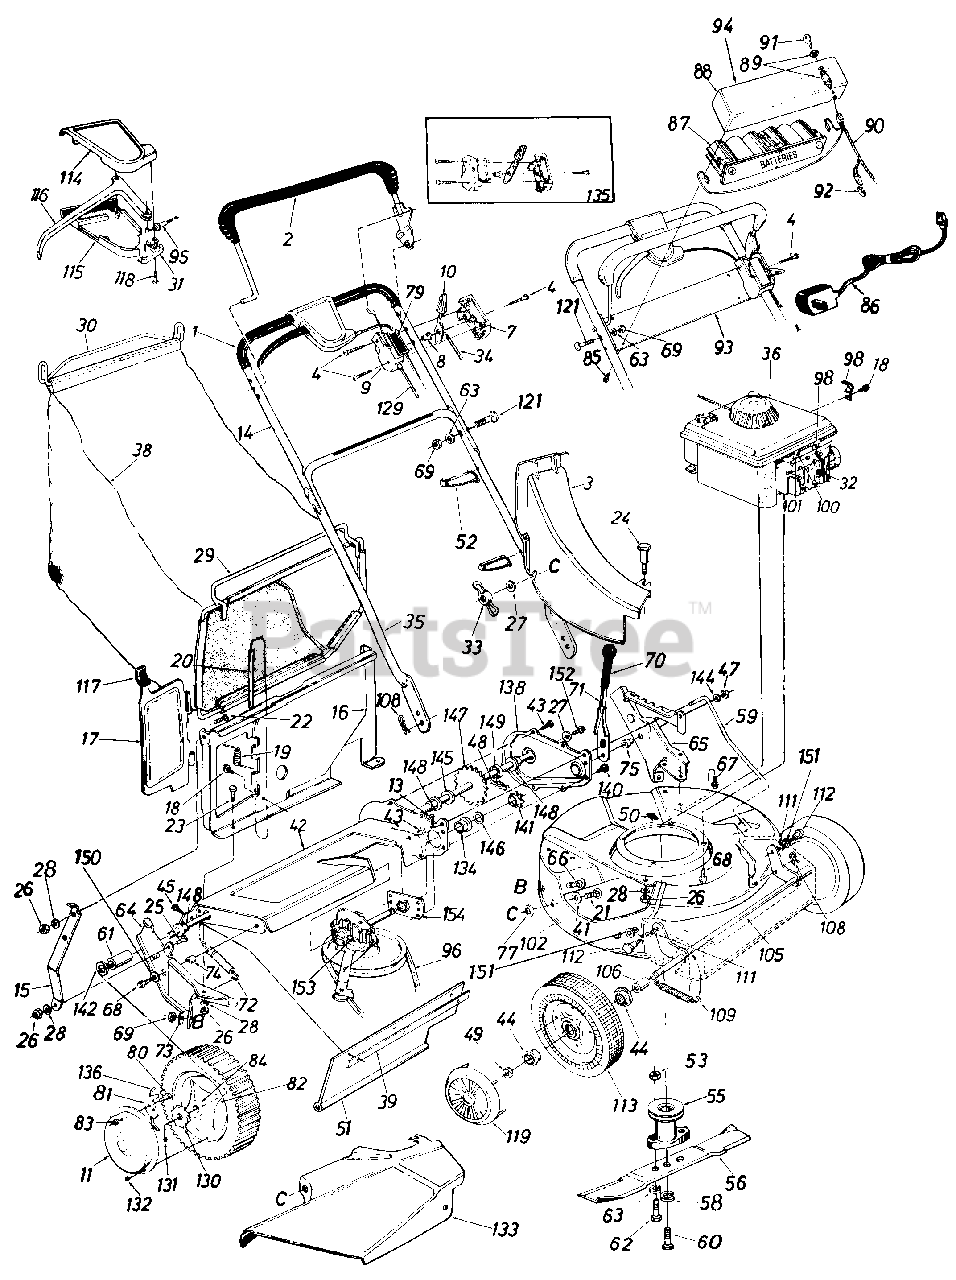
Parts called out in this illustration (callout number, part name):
2	Control Handle Ass'y. L.H.
3	Top Discharge Chute Ass'y.
4	Truss Mach. Scr. #12 x 1.50" Lg.
7	Control Panel Half
8	Control Disc Pin
9	Clutch Panel Half
10	Throttle Control Lever
11	Hub Cap
13	Cotter Pin 3/32" Dia. x .75"
14	Upper Handle-Chrome
15	Panel Support Brkt.
16	Top Catcher Panel
17	Top Door
18	Hex B-Tap Scr. #10 x .38"
19	Torsion Spring
20	Pivot Pin
21	Carriage Bolt 1/4-20 x .62"
22	Truss Mach. Scr. 1/4-20 x 3/4" Lg
23	Hex Bolt 1/4-20 x .50" Lg.
24	Shoulder Bolt .312 Dia. x .18 Lg. Special
25	Hex Bolt 1/4-20 x .62" Lg.
26	Hex Nut 1/4-20 Thd.
27	Bell-Wash. 1/4" I.D.
28	L-Wash. 1/4" I.D.*
29	Front Grass Catcher Frame
30	Grass Catcher Handle
31	S.P. Control Cover
32	Spark Plug Insulator
33	Wing Nut
34	Throttle Control Wire 58"
35	Lower Handle-Chrome
36	Engine
38	21" Top Discharge Grass Bag
39	Retaining Strip
41	Fl-Wash. .344" I.D. x .62"
42	Chain-Axle Ass'y.
43	Hex B-Tap Scr. 1/4" x .38" Lg.
44	Flange Ball Bearing 1/2" I.D.
45	Hex AB-Tap Scr. 1/4 x .62"
47	Hex Patch L-Nut 3/8-24 Thd.
48	#48 Chain .500" Pitch x .30 Links
49	Hex L-Nut 1/2-20 Thd.
51	Rear Flap 3.75" x 17.30" Lg.
52	Cable Tie
53	Hex Nut 5/16-24 Thd.
55	Blade Adapter w/Pulley
56	21" Blade
58	Bell-Wash. .39" I.D. x 1.380" O.D.
59	Height Adj. Rod 19.42" Lg.
60	Hex Bolt 3/8-24 x 2.25" Lg. (Grade 5)
61	Spacer .513" I.D. x .703" O.D. x .69" Lg.
62	Hex Bolt 5/16-24 x 1.00" Lg. (Grade 5)
63	L-Wash. 5/16" I.D.
64	R.H. Handle Wheel Brkt. Ass'y.
65	L.H. Handle Wheel Brkt. Ass'y.
66	Carriage Bolt 5/16-18 x .62"
67	Hex Wash. Hd. B-Tap Scr. 5/16-1 8
68	Hex Wash. Hd. TT-Tap Scr. 3/8-1 6
69	Hex Nut 5/16-18 Thd.
71	Height Adj. Lever
72	Extension Spring .50" O.D. x 3.80" Lg.
73	Bell-Wash. 5/16" I.D.
74	Spacer .385" I.D. x .502" O.D. x .270" Lg.
75	Shld. Spacer .500" Dia. x .100
77	Bolt Retainer 1/4 x-.50" O.D.
79	Control Label
80	Shld. Scr. .342" Dia. x .268
81	Pawl
82	Wheel Ass'y. Comp.-Rear 8 x 1 .75
83	Hex Ins. L-Nut 1/4-20 Thd.
84	Flange Ball Bearing 1/2" I.D.
85	Truss Hd. Scr. #12 x 1.5" Lg.
86	Battery Charger
87	12 Volt Battery
88	Upper Battery Tray
89	Key Switch
90	Wire Harness
91	Key
92	Plug
93	Lower Battery Tray
94	Instruction Label
95	S.P. Cable 50" Lg.
96	"V"-Belt
98	Casing Clamp
100	Hex B-Tap Scr. #10 x .62"
101	Casing Clamp
106	Sleeve .526" I.D. x .690" O.D. x .880" Lg.
108	Intern. Cotter Pin 5/16" Dia.
109	Extension Spring .50" O.D. x 3.20" Lg.
111	Intern. L-Wash. 3/8 I.D.
112	Shld. Bolt .623" Dia. x .425
113	Front-Wheel Ass'y. Comp. 7x 1.50
114	Self-Propelled Control Cover
115	Self-Propelled Control Cover
116	Control Lever
117	Door Grip
118	Fl-"C"-Sunk Hd. Tap Scr. #10 x .75" Lg.
119	Hub Cap-Plastic
121	Curved Carr. Bolt 5/16-18 x 1.38" Lg.
129	Control Cable-43" Lg.
130	Ratchet Wheel 1.62" O.D.
131	Cotter Pin 1/8" Dia. x 1.00" Lg.*
132	Pan Hd. Tap Scr. #12 x .50" Lg.
133	Side Chute Deflector Ass'y
134	Flange Bearing
135	Kit-Control Housing Comp.
136	Spring-Nylon
138	Chain Cover
140	Hex Wash. S-Tap Scr. 1/4-20 x.50" Lg.
141	Sprocket-Shaft Ass'y.
142	Fl-Wash. .510" I.D. x 1.0" O.D.
144	Fl-Wash. .385" I.D. x .87" O.D.
145	Fl-Wash. .51" I.D. x 1.0" O.D.
146	Fl-Wash. 3/8" I.D.
147	Rear Shaft Ass'y. 21.94" Lg.
148	Hex Flange Bearing .506" I.D. Plastic
149	Fl-Wash. .531" I.D. x .930" O.D.
150	Fl-Wash. .531" I.D. x 1.251' O.D.
151	Flanged Nyliner Brg.
152	Hex Bolt 1/4-20 x .62" Lg. (Grade 5)
153	Transmission Comp.
154	Hex Bearing Cup
